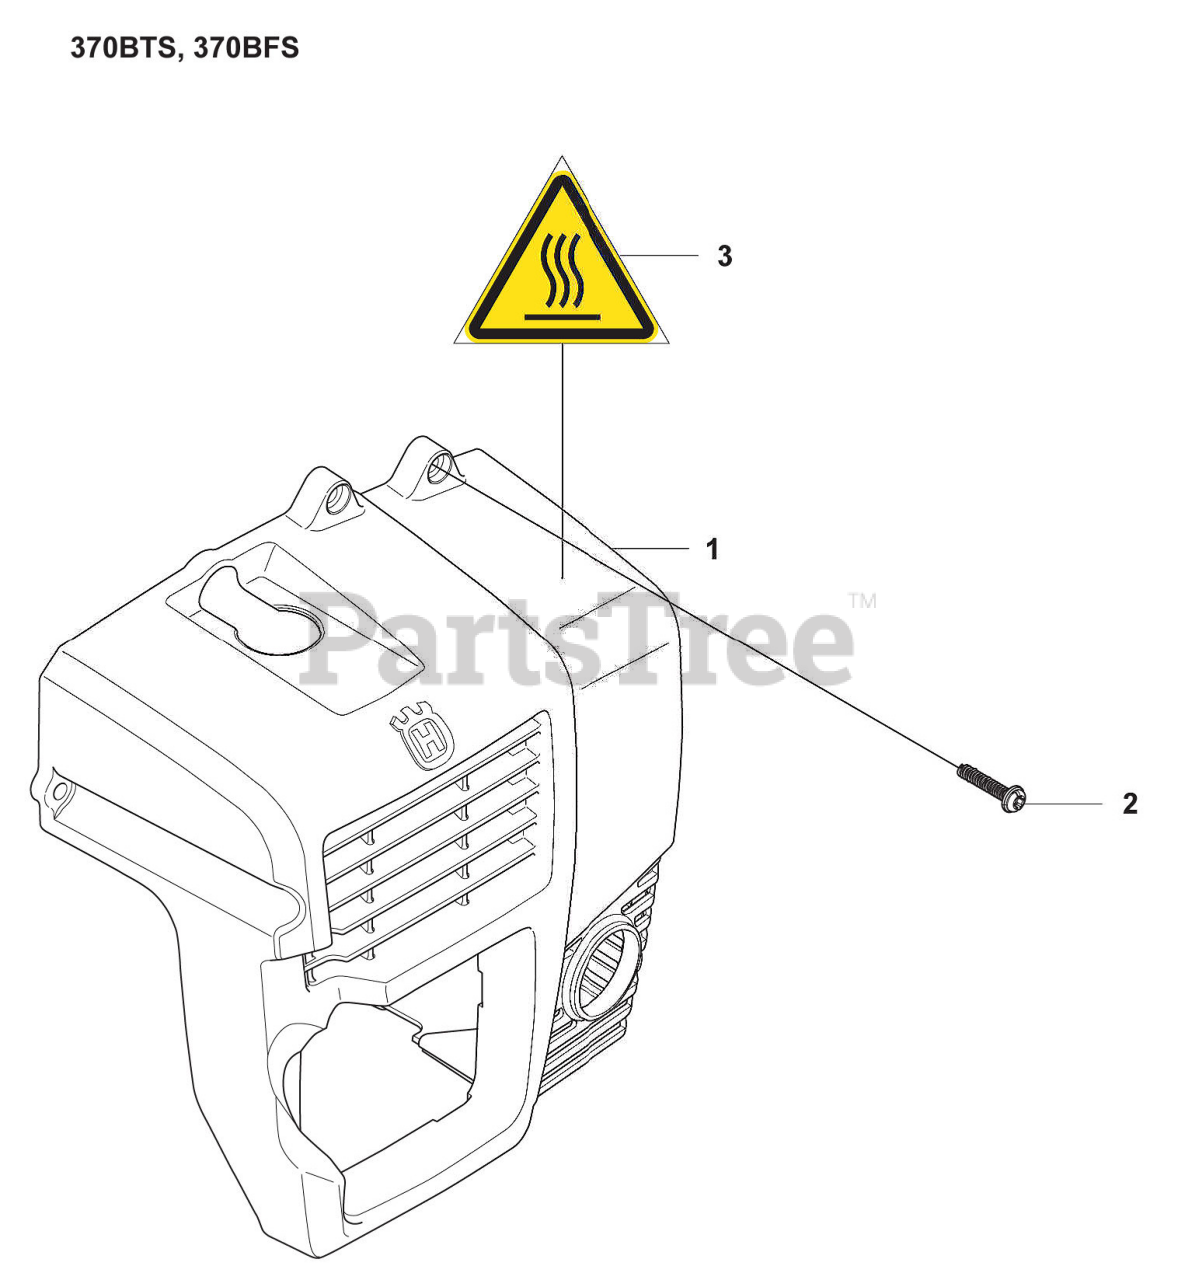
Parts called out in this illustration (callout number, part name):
1	ENGINE COVER
2	Screw
3	RP_LABEL, HOTMARK
